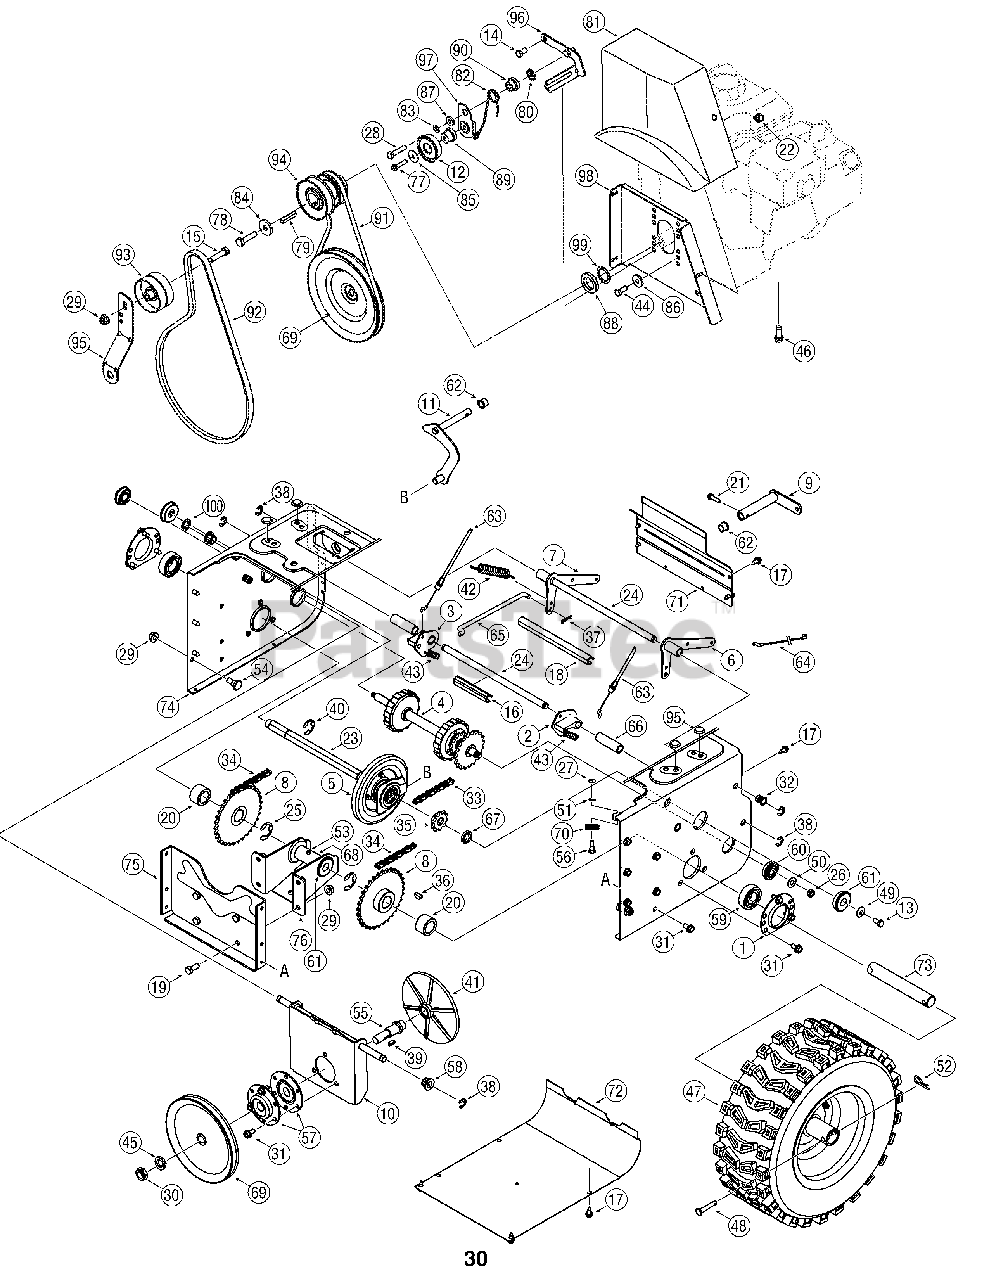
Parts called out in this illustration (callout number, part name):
1	Housing, Bearing
2	Dogg, Steering Drive, LH
3	Dogg, Steering Drive, RH
4	Shaft Assembly, Steering
5	Assembly, Friction Wheel
6	Bracket, Auger Actuator
7	Bracket, Drive Actuator
8	Sprocket, 32T
9	Arm, Shift
10	Brkt, Friction Drive Suprt.
11	Rod Assembly, Shift
12	Idler Pulley Assembly
13	Screw, Hex Cap Lock,
14	Screw, Hex Cap, 5/16-24
15	Scr, Hex Cap, 3/8-16 x 1.75
16	Spcr., .51 ID x 3.66 Lg.
17	Screw, Hex Wash.
18	Spcr., .51 ID x 7.895 Lg.
19	Screw, Hex Cap, 3/8-16
20	Spcr., 1.0 ID x 1.50 OD
21	Screw, Hex, 1/4-20 x 1.00
22	Screw, Hx Wash Hd Tapp
23	Shaft, Hex Drive
24	Shaft, Actuator
25	Ring, Retainer
26	Nut, Hex Insert Jam Lock
27	Nut, Hex, 1/4-28 GR5
28	Screw, Hex Cap, 5/16-24 x 1.50
29	Nut, Hx Flnge Insert Lk
30	Nut, Hx Insert Jam Lk
31	TT Screw, 5/16-18 x .750
32	Nut, Insert 3/8-16
33	Chain, Endless, #41 x 36L
34	Chain, #420 x 40L
35	Sprocket, #41 x 10T
36	Key, Woodruff
37	Pin, Internal Cotter
38	E-Ring
39	Key, Hi-Pro, 3/16 x 5/8
40	Ring, Retaining
41	Plate, Drive
42	Spring, Extension
43	Spring, Extension
44	Screw, Hex Cap, 5/16-24 x .750
45	Washer, Lock, 5/8
46	Screw, 3/8-16 x 1.00
47	Wheel Ass’y. -LH
47	Wheel Ass’y. -RH
48	Pin, Clevis
49	Wsh, Bell., .34 x .872 x .06
50	Wash, .406 x .875 x .059
51	Washer, Lock, 1/4
52	Pin, Internal Cotter
53	Fitting, Lube, 3/16 Drive
54	Screw, Shldr., .498 x .34
55	Spindle, Drive Plate
56	Screw, Hex Shldr., 1/4-28
57	Ass’y, Bearing/Housing
58	Bearing, Hex Flange
59	Bearing, Self Aligning
60	Bearing, Ball
61	Bearing, Ball
62	Bush, Flg, .5 ID x .627 OD
63	Cable, Steering
64	Cable, Auger Idler
65	Rod, Drive Clutch
66	Spcr., .514 x .632 x 2.44
67	Spacer, .675 x 1.0 x .23
68	Spcr, .6725 x 1.125 x 2.48
69	Pulley, Drive
70	Roller, Cable
71	Cover, Upper Frame
72	Cover, Lower Frame
73	Axle, Wheel, 33"
74	Frame, Transmission
75	Bracket, Frame Support
76	Bracket, Axle Support
77	Screw, 1/4-20 x 1.25
78	Hex Hd. Screw, 3/8-24 x 1.50 GR8
79	Key, Square, 1/4 x 1.5
80	Nut, Push
81	Cover, Belt
82	Torsion Spring, .850 dia. x .333 lg.
83	Washer, Lock, 5/16
84	Washer, Flat, .406 x 1.25
85	Washer, Flat, .265 x 1.0 x .030
86	Spacer, Shoulder
87	Shoulder Spacer, .3175 x .500 x .094
88	Spacer, 1.004 x 1.375 x .25
89	Shoulder Spacer, .260 x .785 x .538
90	Shoulder Spacer, .340 x 1.00
91	V-Belt, 3/8 x 34.4
92	V Belt,1/2 x 42
93	Pulley, Flat Idler, 2.75 OD
94	Double Pulley, 3.25 x 2.75
95	Bracket, Auger Idler
96	Belt Keeper Bracket
97	Idler Drive Wheel Bracket
98	Belt Cover Bracket
99	Washer, Flat, 1.015 x 1.375 x .062
100	Speed Nut, .500
